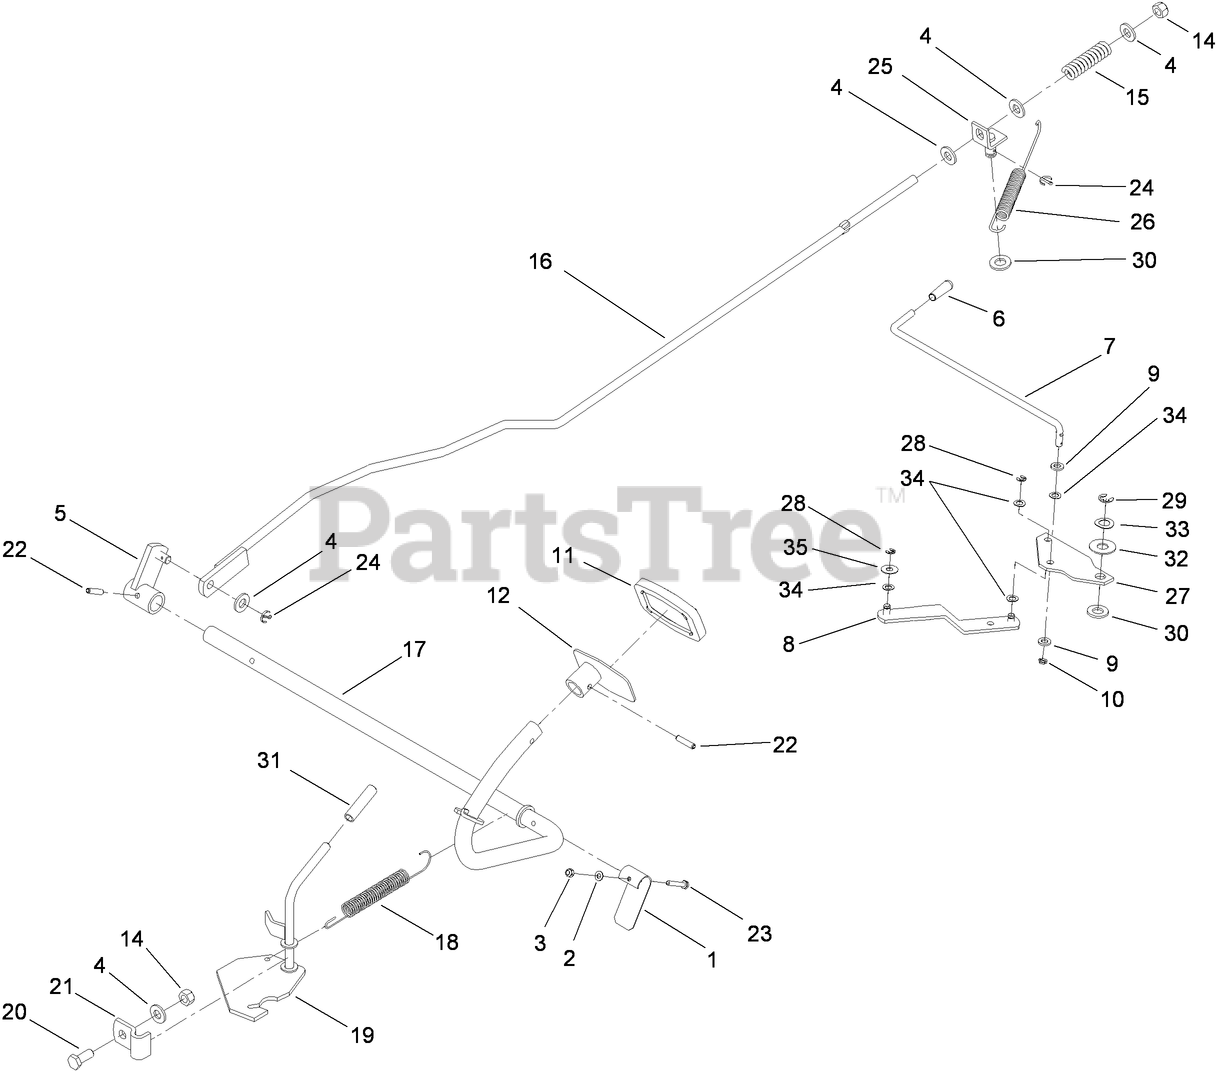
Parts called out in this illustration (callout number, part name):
1	LEVER-SPRING
2	WASHER
3	NUT-HEX
4	WASHER-PLAIN
5	BRACKET-ROD, BRAKE
6	CAP-BYPASS LEVER, HYDRO
7	ROD-LEVER, BYPASS
8	LEVER-BYPASS
9	WASHER
10	PIN-COTTER
11	PAD-PEDAL
12	PEDAL-BRAKE
14	NUT-LOCK, NI
15	SPRING-BRAKE
16	ROD-CONNECTING, BRAKE
17	SHAFT-BRAKE
18	SPRING-BRAKE, HAND
19	LEVER-BRAKE, HAND
20	SCREW-HH
22	PIN-SPRING
23	SCREW-HEX
24	PIN-COTTER
25	BRACKET-ROD, BRAKE
26	SPRING
27	Plate-Bypass
28	STIRRUP
29	E-CLIP
30	WASHER-FLAT
32	Washer
34	Washer
